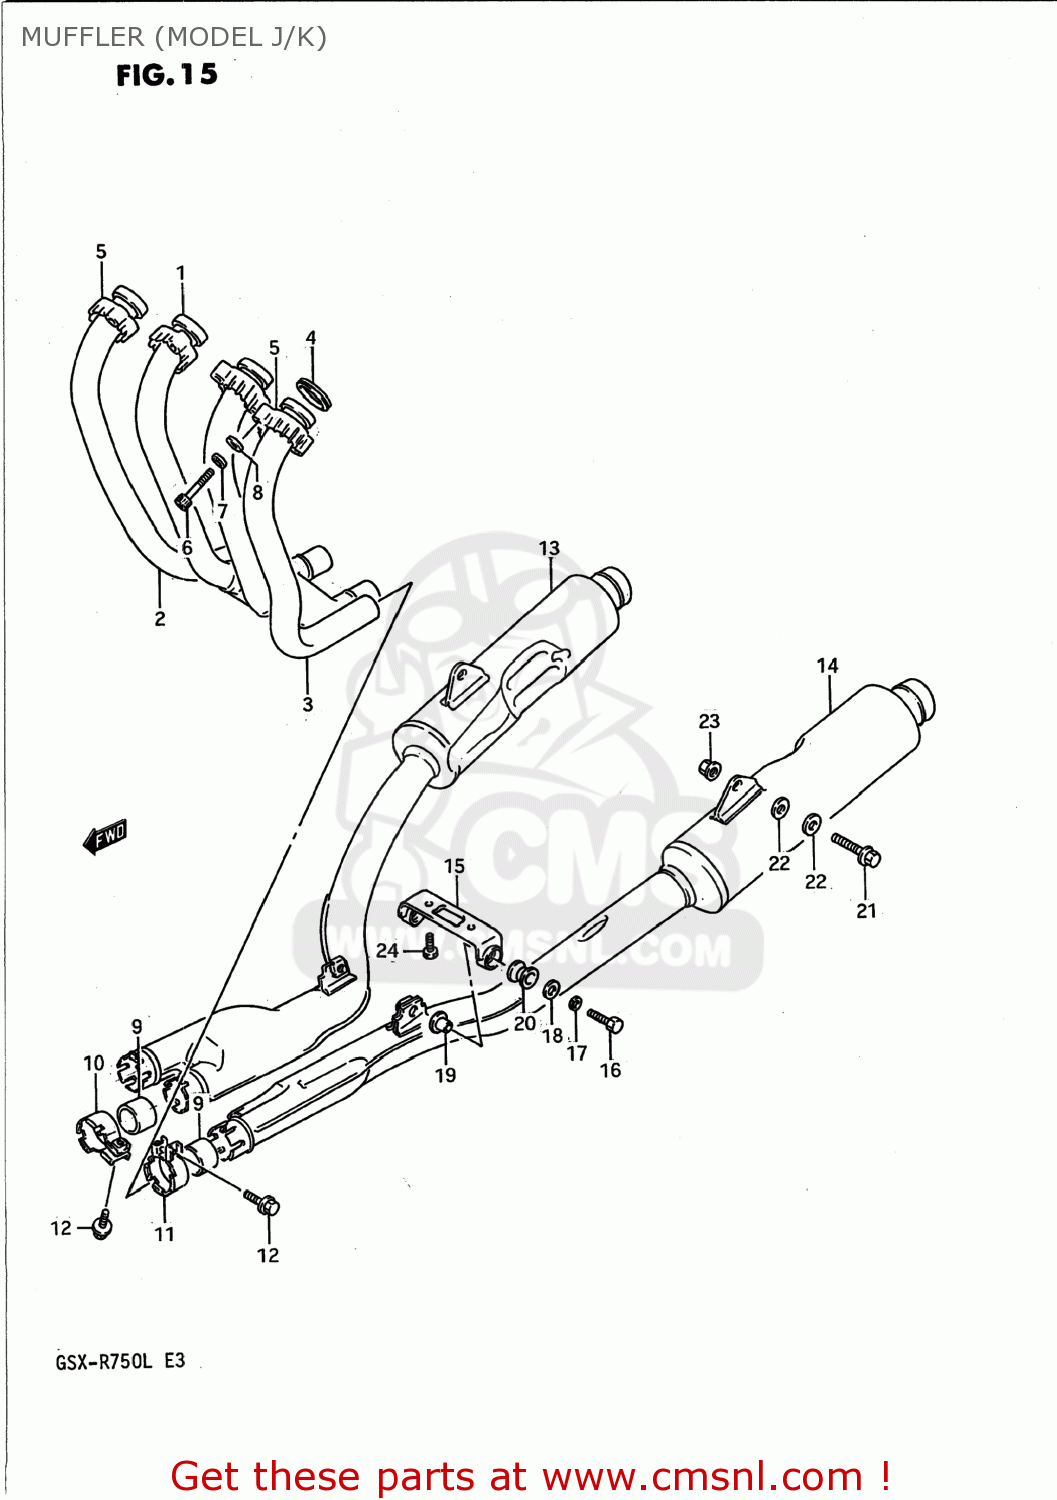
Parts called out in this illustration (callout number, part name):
1	PIPE,EXHAUST
2	PIPE,EXHAUST
3	PIPE COMP,EXHAUST,LEFT
4	GASKET,EXHAUST (NAS)
5	CLAMP,EXHAUST PIPE
6	BOLT 8X35
7	WASHER
8	WASHER
9	CONNECTOR,MUFFLER
10	CLAMP,MUFFLER
11	CLAMP,MUFFLER
12	BOLT
13	BODY,MUFFLER
14	BODY,MUFFLER
15	DAMPER,MUFFLER
16	BOLT
17	WASHER,LOCK,8.
18	WASHER (8.5X20X1.6)
19	SPACER(8.6X12X17.5)
20	CUSHION
21	BOLT 10X38
22	WASHER (10.5X24X2.3)
23	NUT
24	BOLT(8X20)
